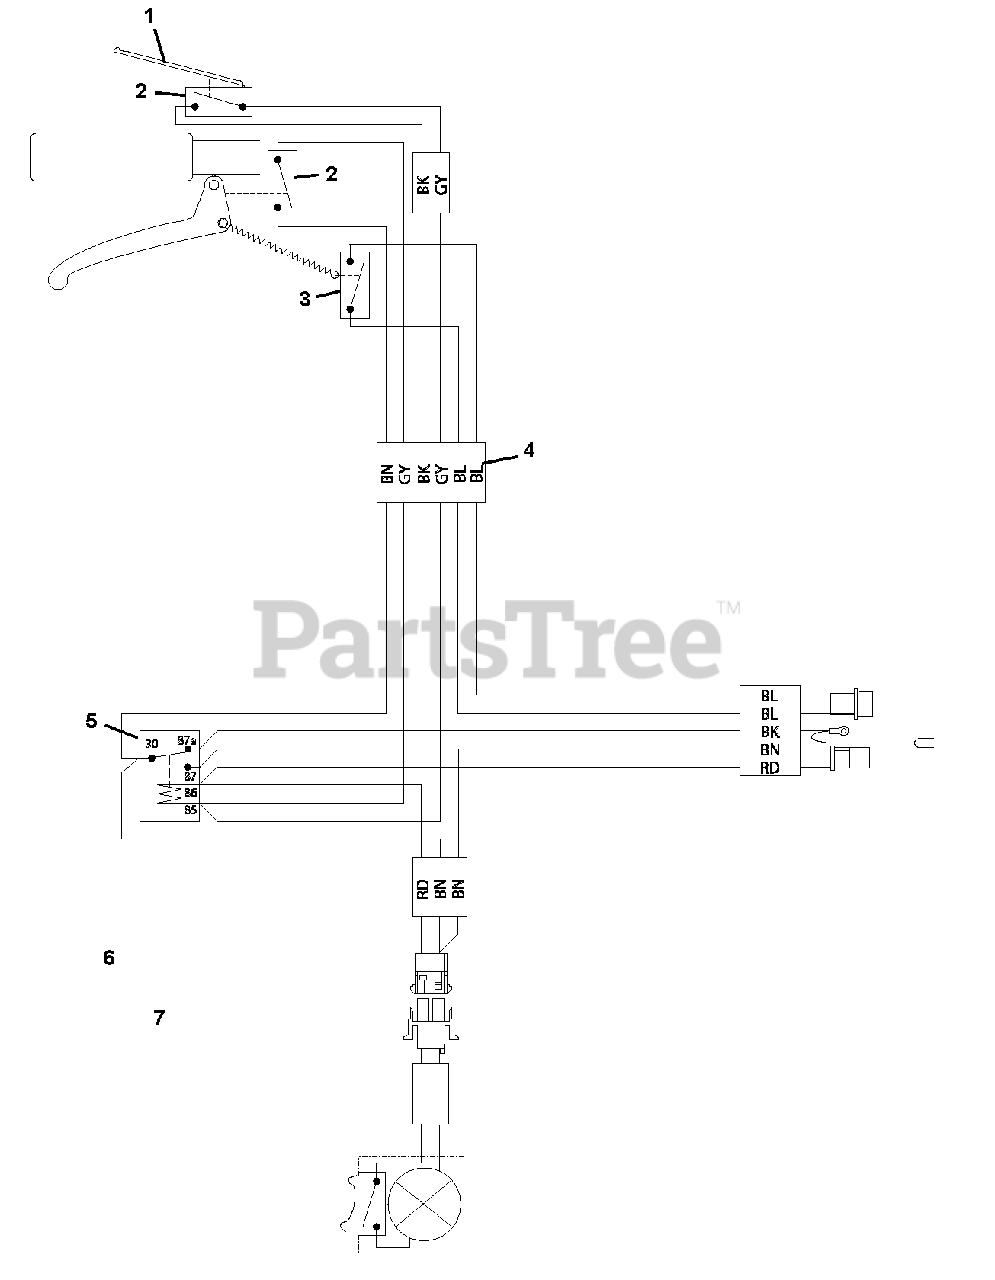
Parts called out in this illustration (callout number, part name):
1	Lever, Emergency
4	Cable Harness
6	Bulb, 12V/55WH3
7	Wire, Harness
